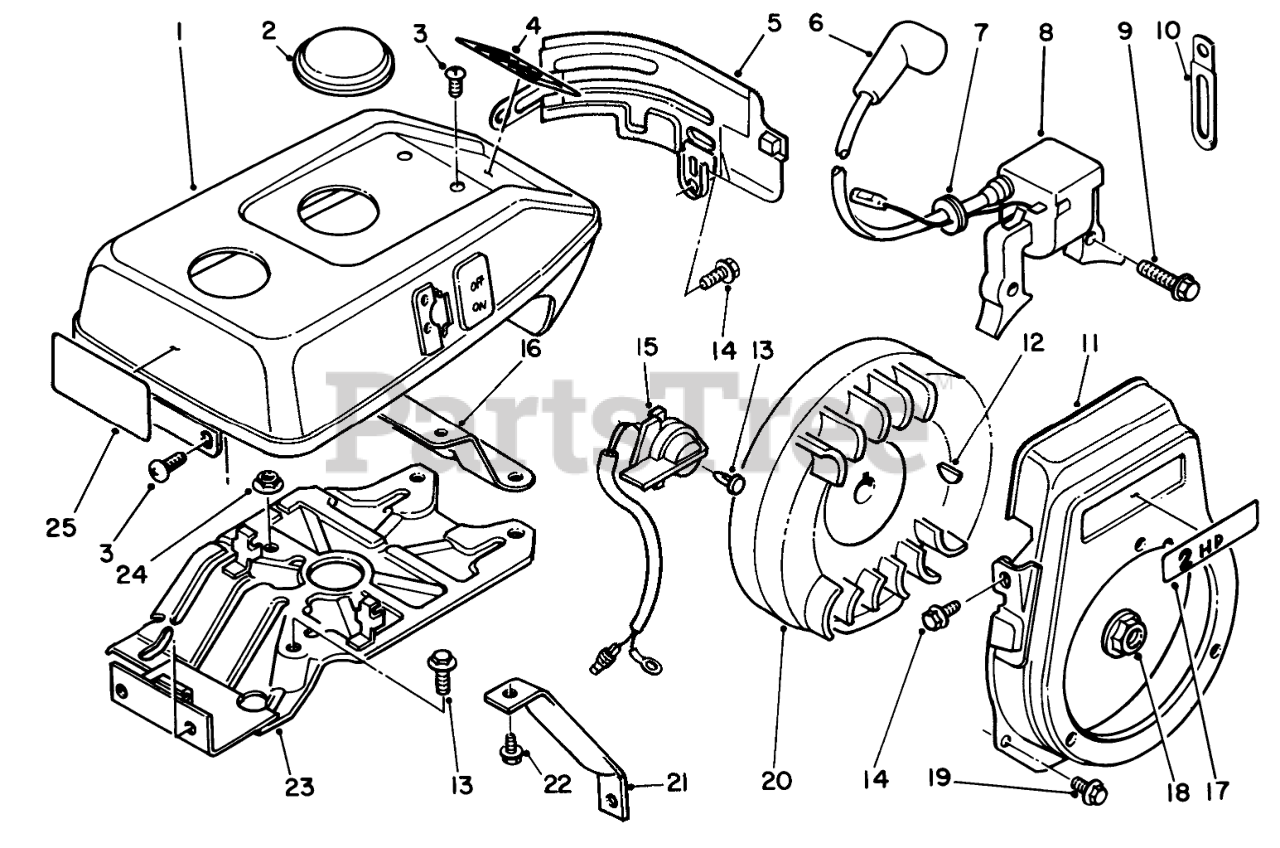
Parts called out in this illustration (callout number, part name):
1	Cover-Engine
3	Screw-Round Phillips Hd.
4	Decal-Toro Logo
5	Cowling-Side
6	CAP-SPARKPLUG
7	Grommet
8	Coil Assembly (Solid State) (Incl. Ref. #6 & 7)
10	CLAMP
11	Cover-Cooling Fan
15	Switch-Engine
16	Bracket-Engine Cover
17	Decal-2 H.P.
20	Rotor
21	Support-Fuel Tank
22	SCREW-HHF
23	Cowling-Upper
25	OPERATING INST DECAL
